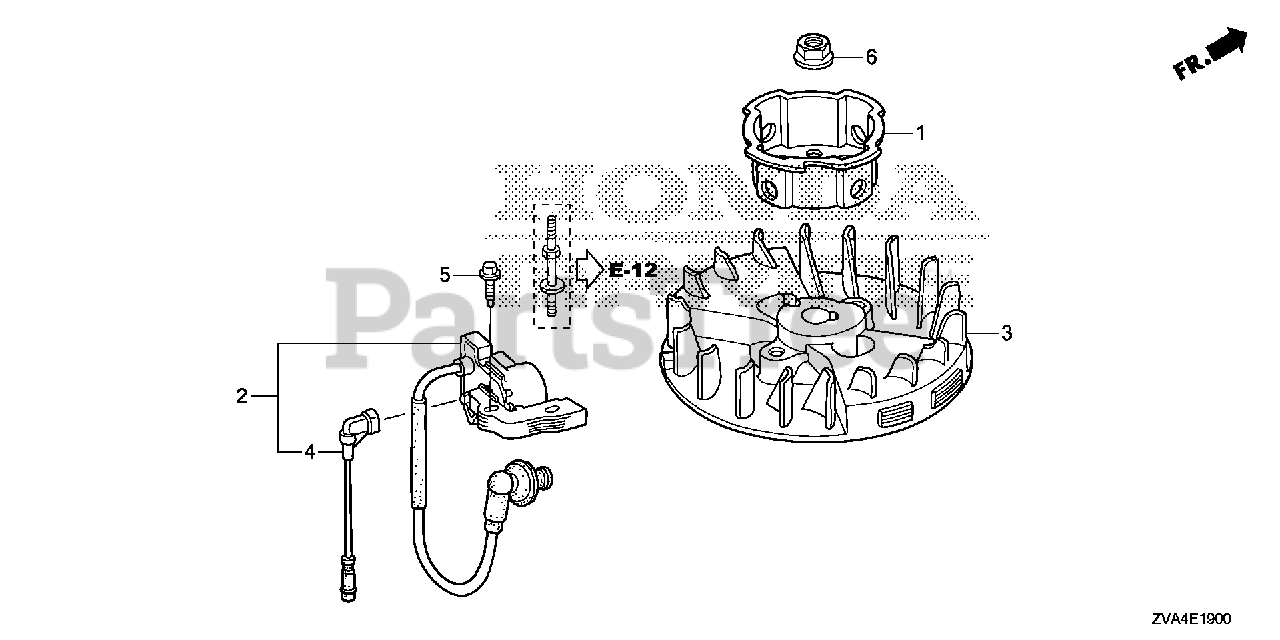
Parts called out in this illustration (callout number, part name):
1	PULLEY, STARTER
2	COIL ASSY., IGNITION
4	WIRE, STOP SWITCH
5	BOLT, FLANGE (5X20) (CT200)
6	NUT, FLANGE (10MM)
